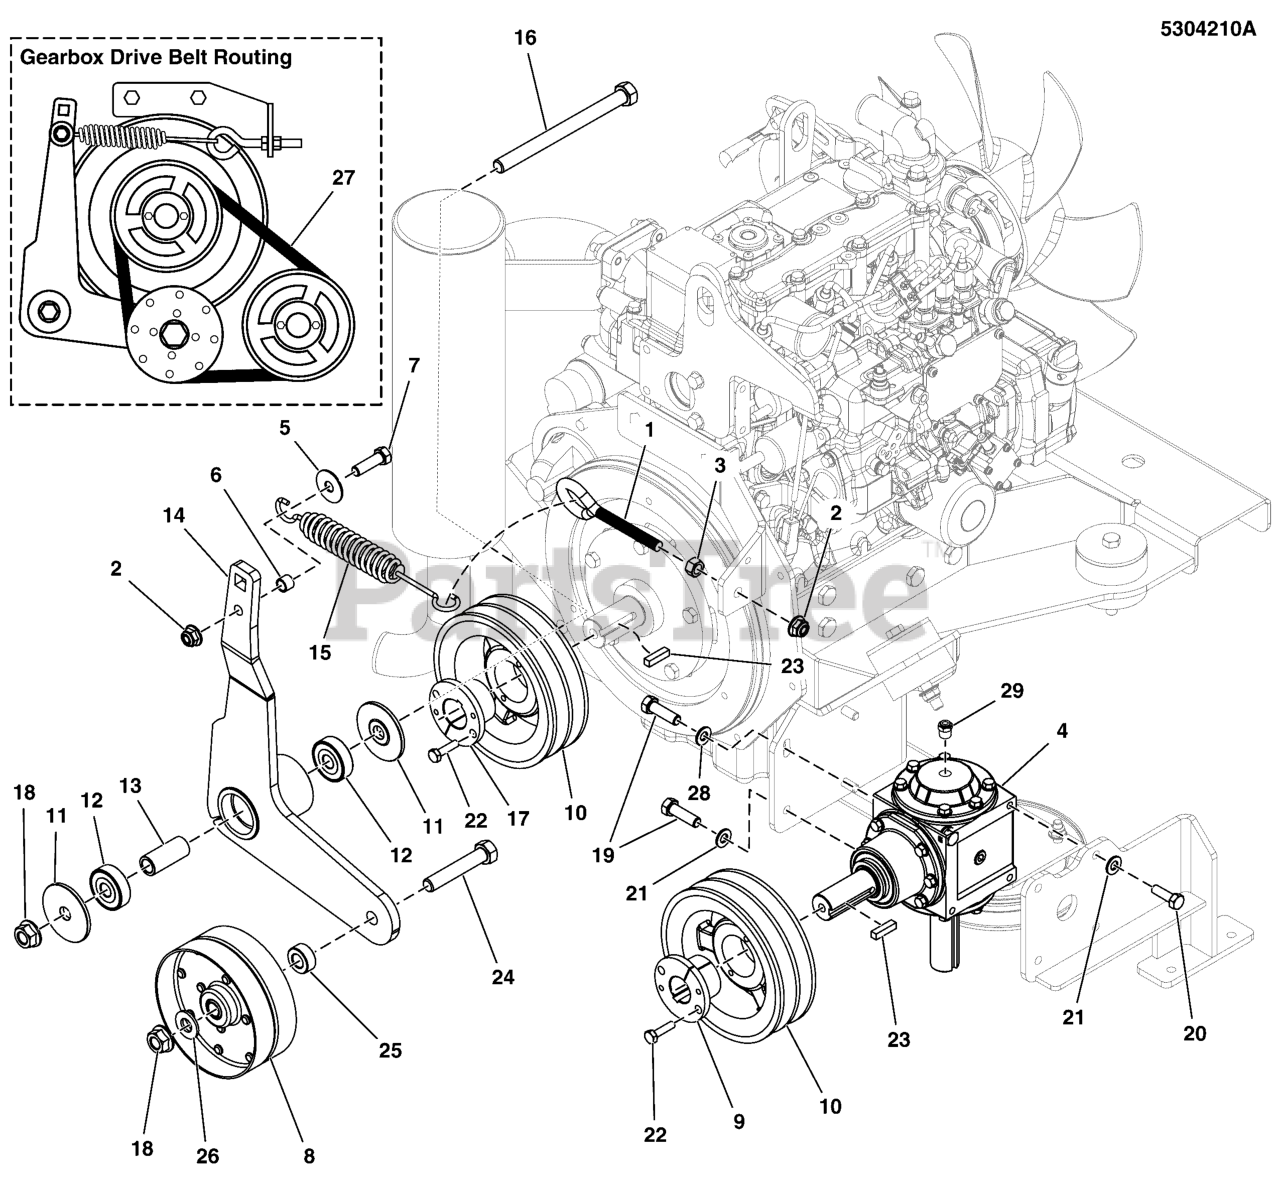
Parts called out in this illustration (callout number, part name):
1	EYE BOLT,3/8-16X4.13,2.33THRD,.75EYE,CZ
2	NUT, 3/8 - 16 HEX NYLOCK FLANGE
3	NUT, 3/8-16 Hex Large Serrated Flange
4	GEARBOX RIGHT ANGLE
5	WASHER, 3/8" Fender
6	SPACER, .38 X .50 X .38, CZ
7	BOLT, 3/8-16 X 1-1/4" GD5 CZ
8	PULLEY, FLAT IDLER, 5"OD X 2" W X .5 ID
9	BUSHING, Tapered Hub
10	PULLEY, DOUBLE, DH4600, 5.95 OD TAPERED
11	SPACER, IDLER ARM, 1/2 X 2.25
12	BEARING, 6203-1/2", SEALED
13	SPACER, .510 X .750 X 1.749, CZ
14	ARM, Idler
15	SPRING-EXT, 1.04 ODX6.935LGX.148WR, BLK
16	BOLT, 1/2-13 X 4-1/2" GD5 YZ
17	TAPER LOCK BUSHING, HQ-1-1/8"
18	NUT, Hex Flange, Nylock, 1/2-13
19	BOLT, 5/16-18 X 1" GRD5 YZ
20	BOLT, 5/16-18 X 3/4 GD5
21	WASHER, 5/16" SAE
22	BOLT, 1/4-20 X 1" GD5 CZ
23	KEY, 1/4" SQ. X 1-1/4
24	BOLT, 1/2-13 X 2-3/4 GD5 CZ
25	SPACER, .52 X 1.00 X .44, CZ
26	WASHER, 1/2 SAE
27	BELT, B-SEC, DOUBLE, BANDED, 41" EL
28	WASHER, 5/16 GRADE 9, FLAT
29	PRESSURE RELIEF VALVE, #410696
